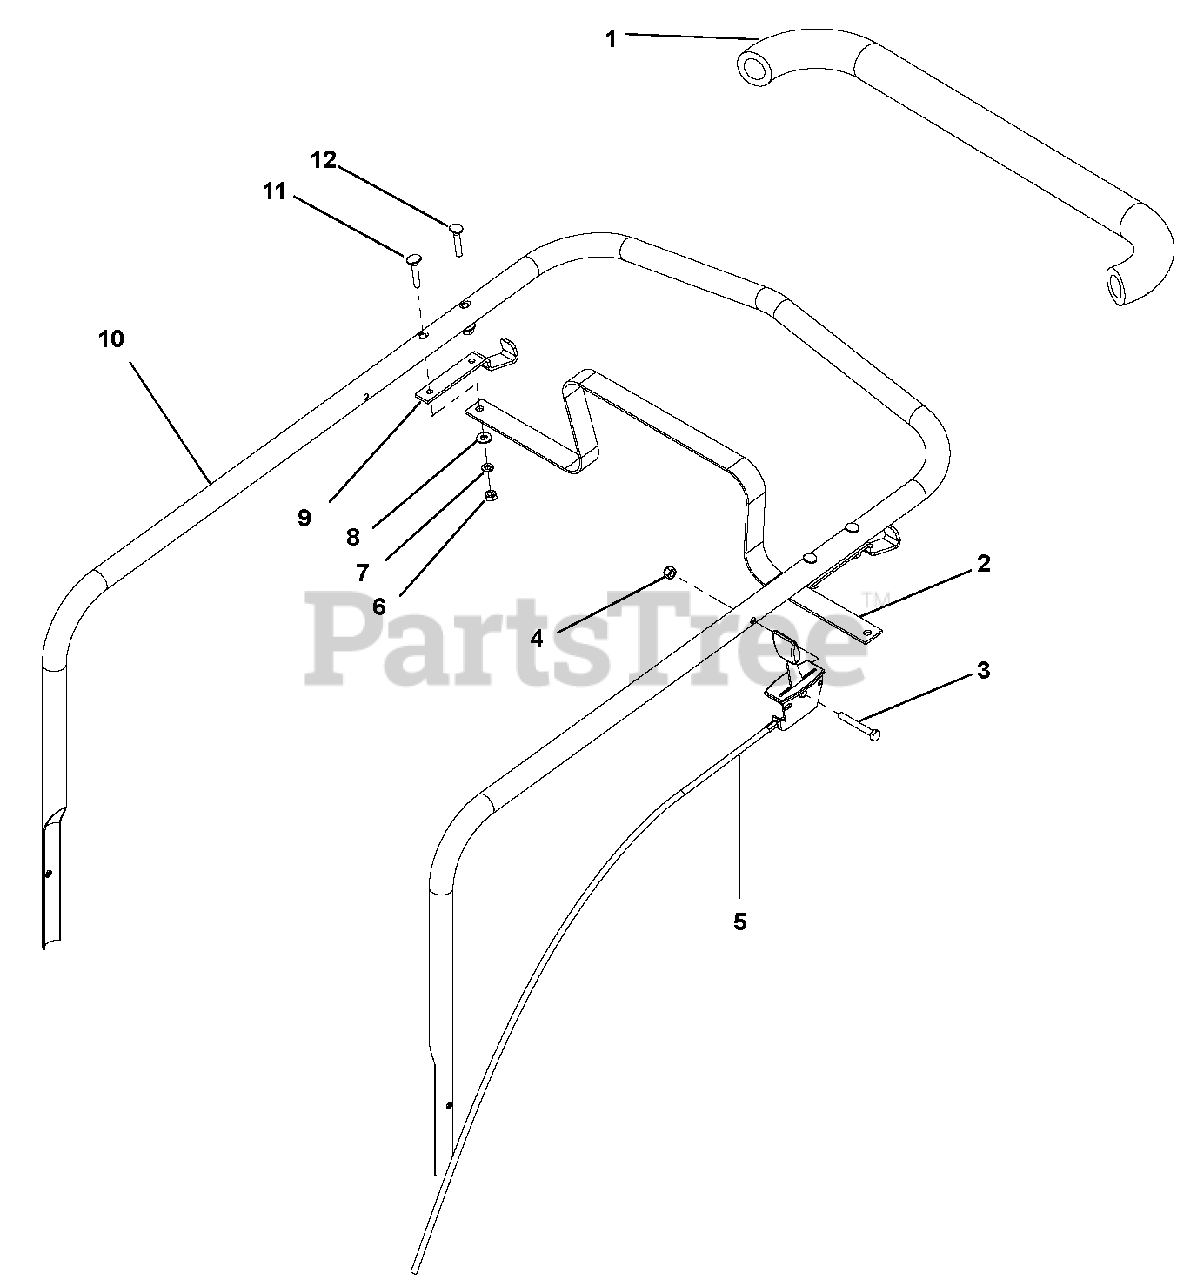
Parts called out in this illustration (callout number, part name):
1	Sleeve, Handle
2	Hose Support Bar, Upper
3	Bolt, Hex .25-20 X 2.00
4	Nut, Locking, Nylon .250-20
5	Throttle, Apv B/S Engine
6	Nut, Hex .25-20
7	Washer, Locking .25 X .062 Regular
8	Washer, Flat, Steel .281 X .62 X .065
9	APV Bag Holder
10	APV Upper Handle
11	Bolt, Cont. Head 1/4-20 X 1.50
12	Bolt, Cont. Head 1/4-20 X 1.75
